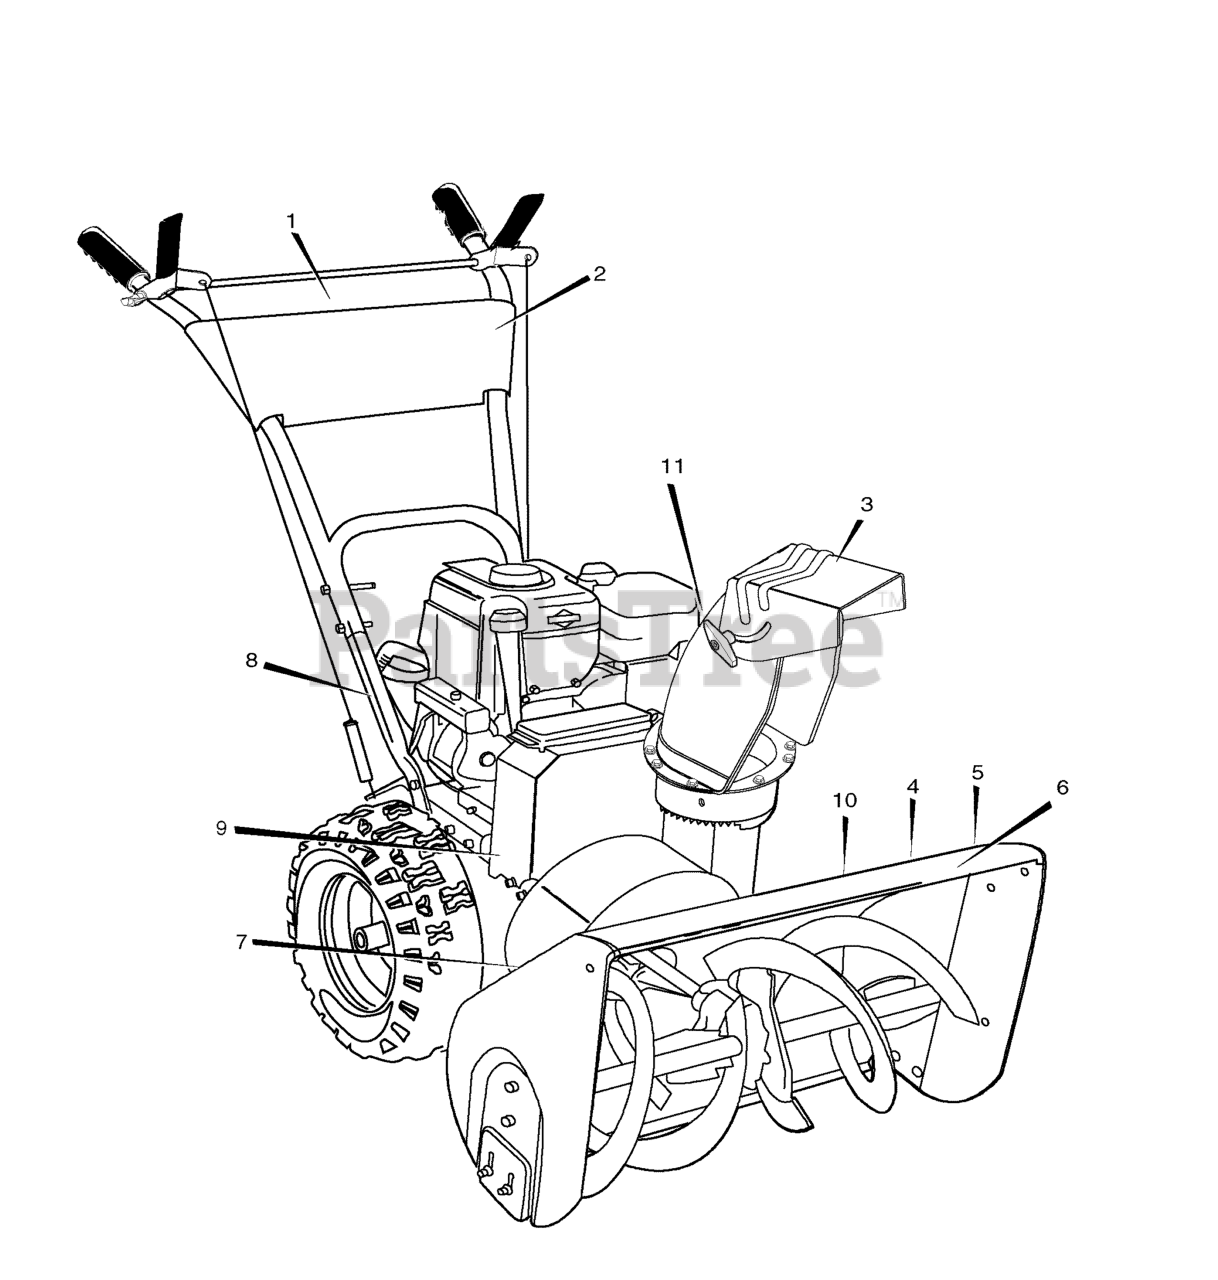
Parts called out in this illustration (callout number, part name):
1	DECAL, HAND CONTROL
2	DECAL, MURRAY ULTRA CONTROL PANEL
3	DECAL, ISO CHUTE CE
4	DECAL, 104db CE
5	DECAL, FACE HEAD PHONES
6	DECAL, MURRAY 8.00/24"
7	DECAL, ISO AUGER CE
8	DECAL, GEAR SELECT
9	DECAL, BELT ADJUSTMENT
10	DECAL, CLEAN & CLEAR BRUSH
11	DECAL, DANGER CHUTE
